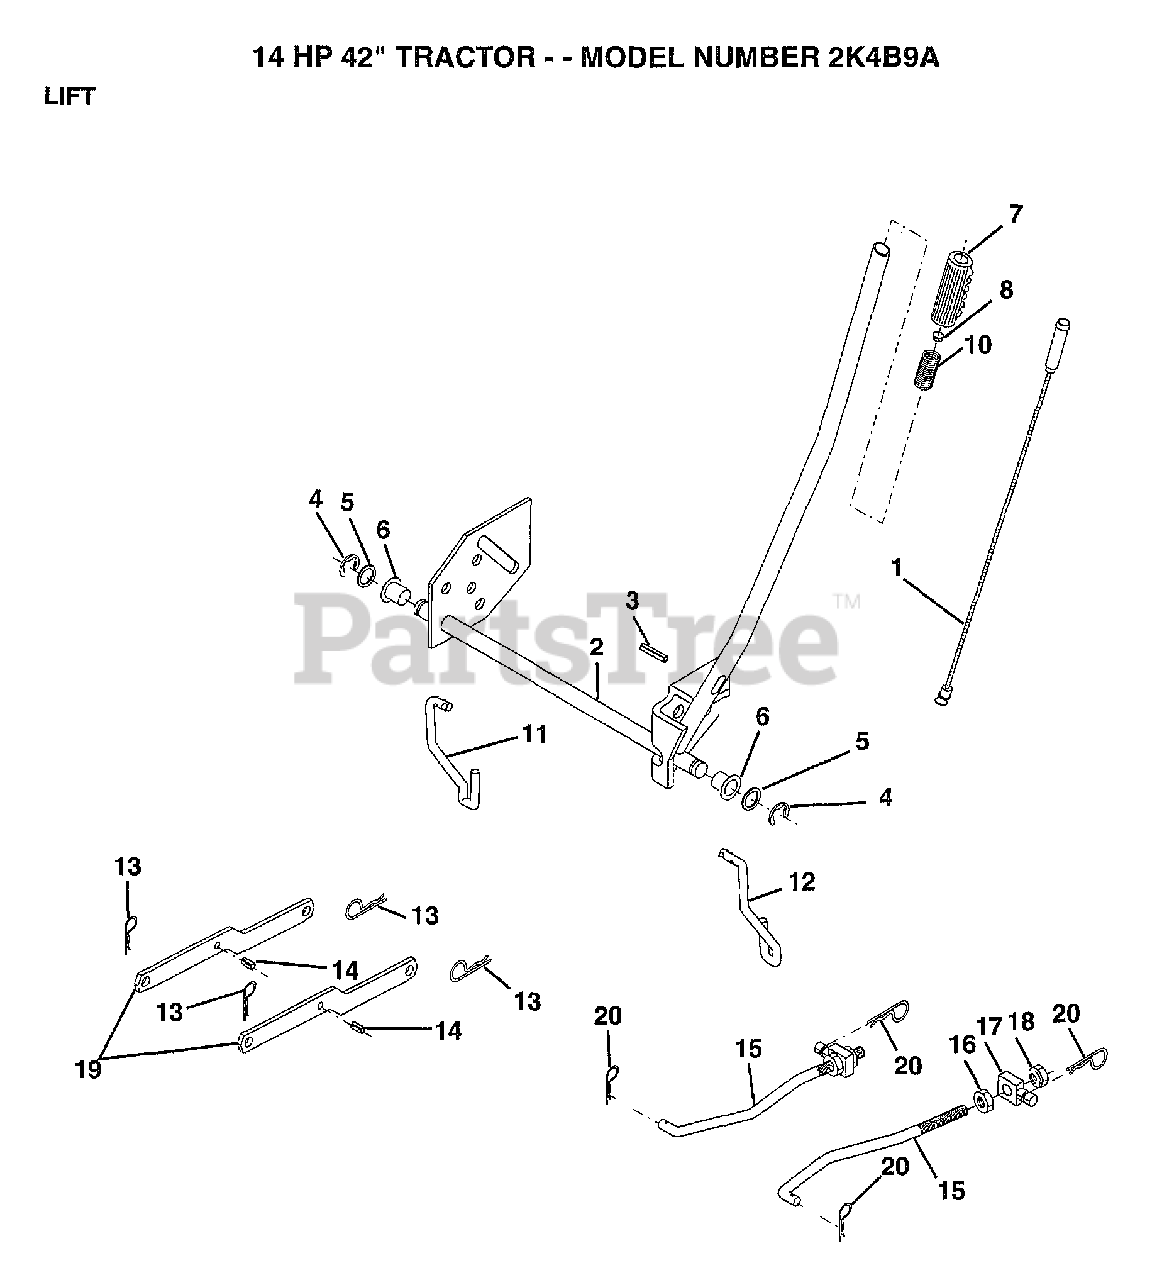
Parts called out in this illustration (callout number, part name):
1	WIRE ASM
3	PIN-GROOVE LT
5	WASHER
6	NYLON BEARING
7	GRIP
11	LINK LIFT LH
12	LIFT LINK RH
14	"PIN,SPRING"
15	LINK.FRONT
16	NUT
17	TRUNION
18	NUT.LK.W/WSH.1/2.
20	RETAINER.SPRING
